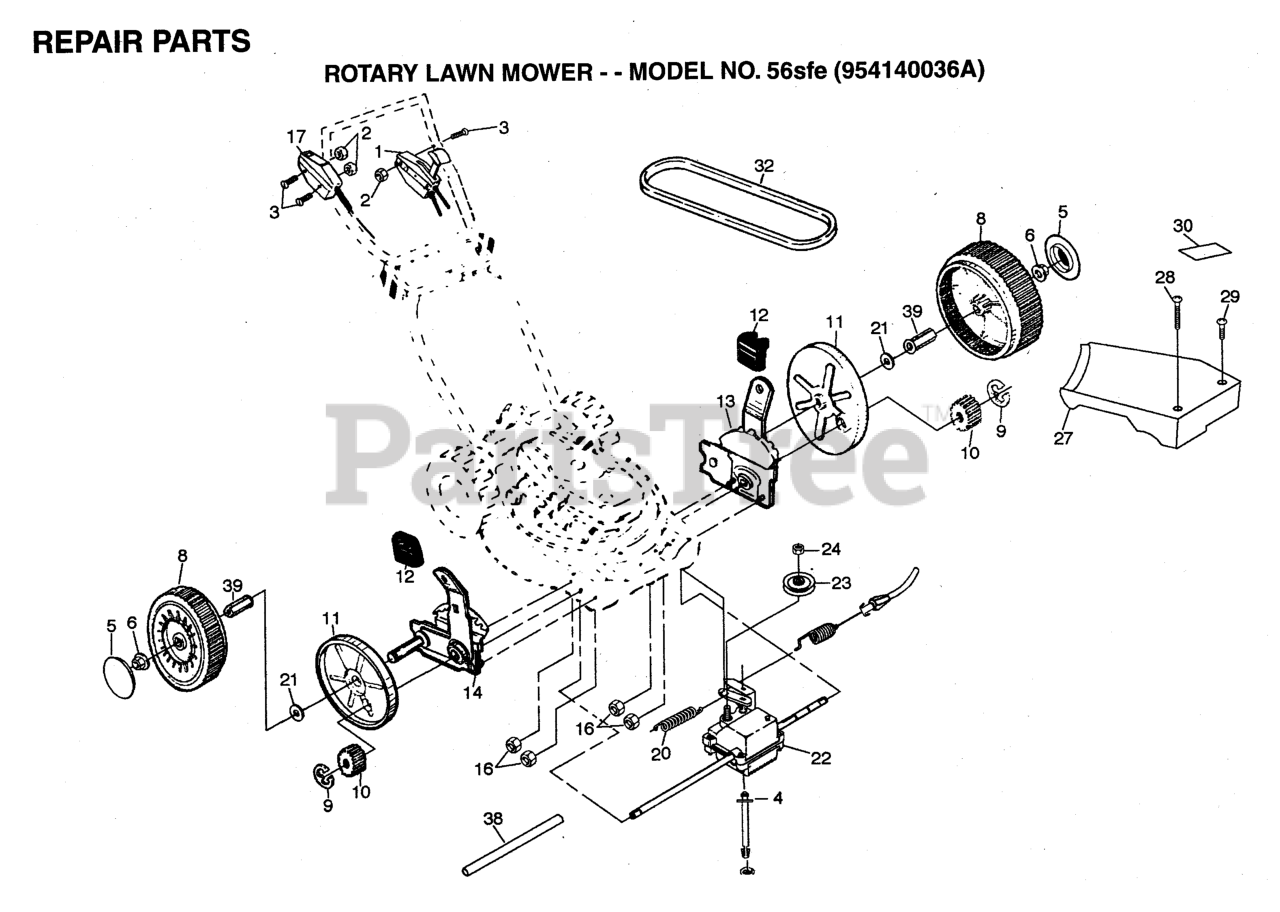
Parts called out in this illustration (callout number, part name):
1	CONTROL DRV 55.13
2	NUT
3	SCREW 1/4-20 X 2.12
4	SPRING RETAINER
5	HUBCAP.8".GREY
6	NUT
9	E-RING 7/16 RE
10	PINION GEAR
11	DUST SHROUD PM
12	SELECTOR KNOB
16	NUT
17	ENGINE ZONE CONTROL CABLE
18	SPRING.EXTENSION
21	WASHER FLUT
22	GEAR CASE ASMBLY
23	PULLEY
24	FLANGED LOCKNUT 3/8-16 ZINC
27	DRIVE COVER-GRAY
29	SCREW.SLOT.TORX.
32	BELT THERM .32
38	DRV SHAFT TUBE PM
39	BUSHING PM
